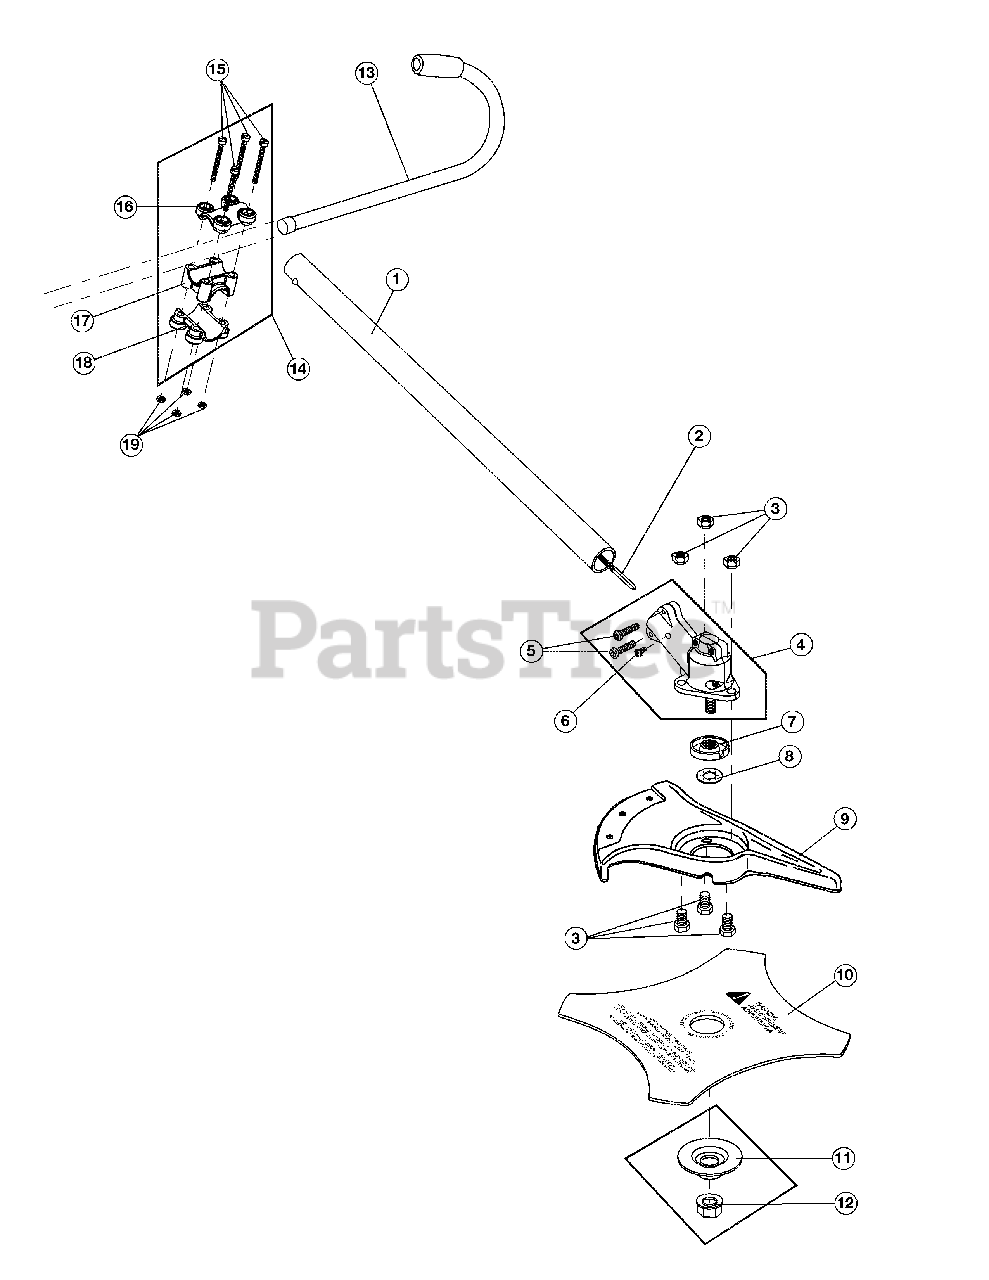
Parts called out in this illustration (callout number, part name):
1	Lower Drive Shaft Housing Assembly
2	Lower Flexible Drive Shaft
3	Shield Mount Screw Assembly
4	2 piece Gearbox Assembly (Incl. 5-6)
5	Gearbox Mounting Hardware
6	Anti-Rotation Screw
7	Blade Driver
8	Palnut
9	Blade Shield/Shield Mount
10	4-Tooth Blade
11	Retaining Washer
13	J-Handle Assembly
14	Handle Bracket Assembly (Incl. 15-18)
16	Upper Handle Clamp
17	Middle Handle Clamp
18	Lower Handle Clamp
